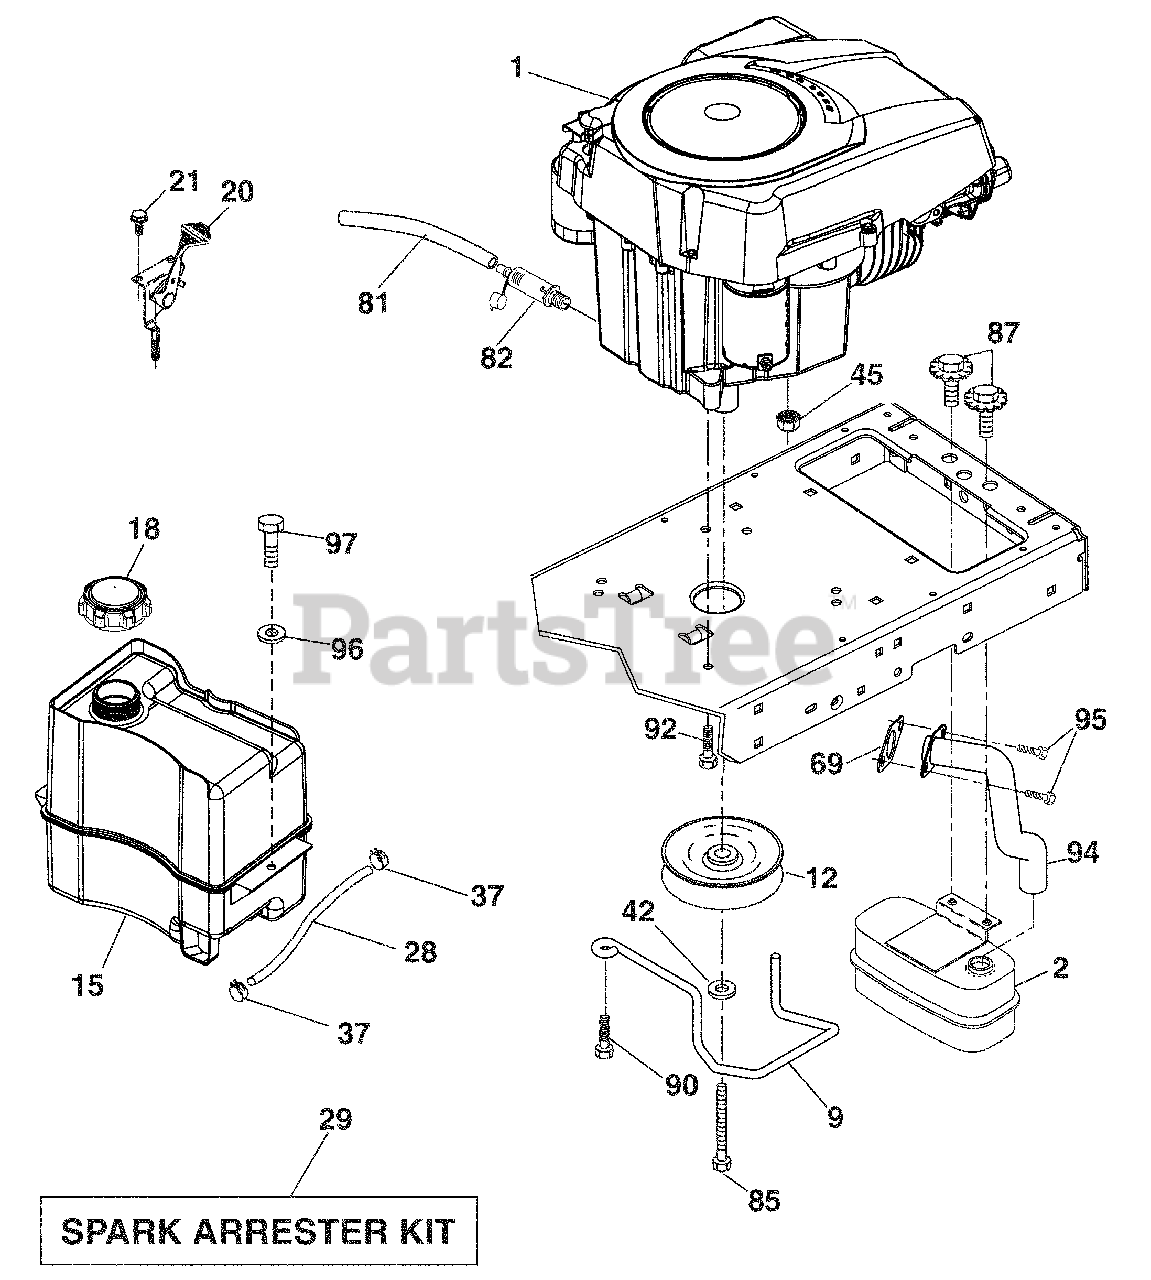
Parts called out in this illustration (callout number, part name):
9	Keeper Belt Engine
12	Pulley Engine
15	Tank Fuel
18	Cap Asm
20	Control Throttle
21	Screw # 10 x 0.750
28	Fuel Line
29	Spark Arrester Kit
37	Clamp Hose
42	Washer Lock 7/16
45	Nut Keps Hex 1/4-20 unc
81	Tube Drain Oil Easy
82	Plug Drain Oil
85	Bolt Hex 7/16-20 x 4 x Gr. 5-1.5 Thr
87	Bolt 5/16-18 UNC x 3/4 w/Sems
90	Screw 3/8-16 x 1
92	Screw 3/8-16 x 1
94	Tube Exhaust
95	Screw Socket Hd. 5/16-18 x .75
96	Washer 9/32 x 7/8 x 16 Ga.
97	Screw 1/4-20 x 3/4
